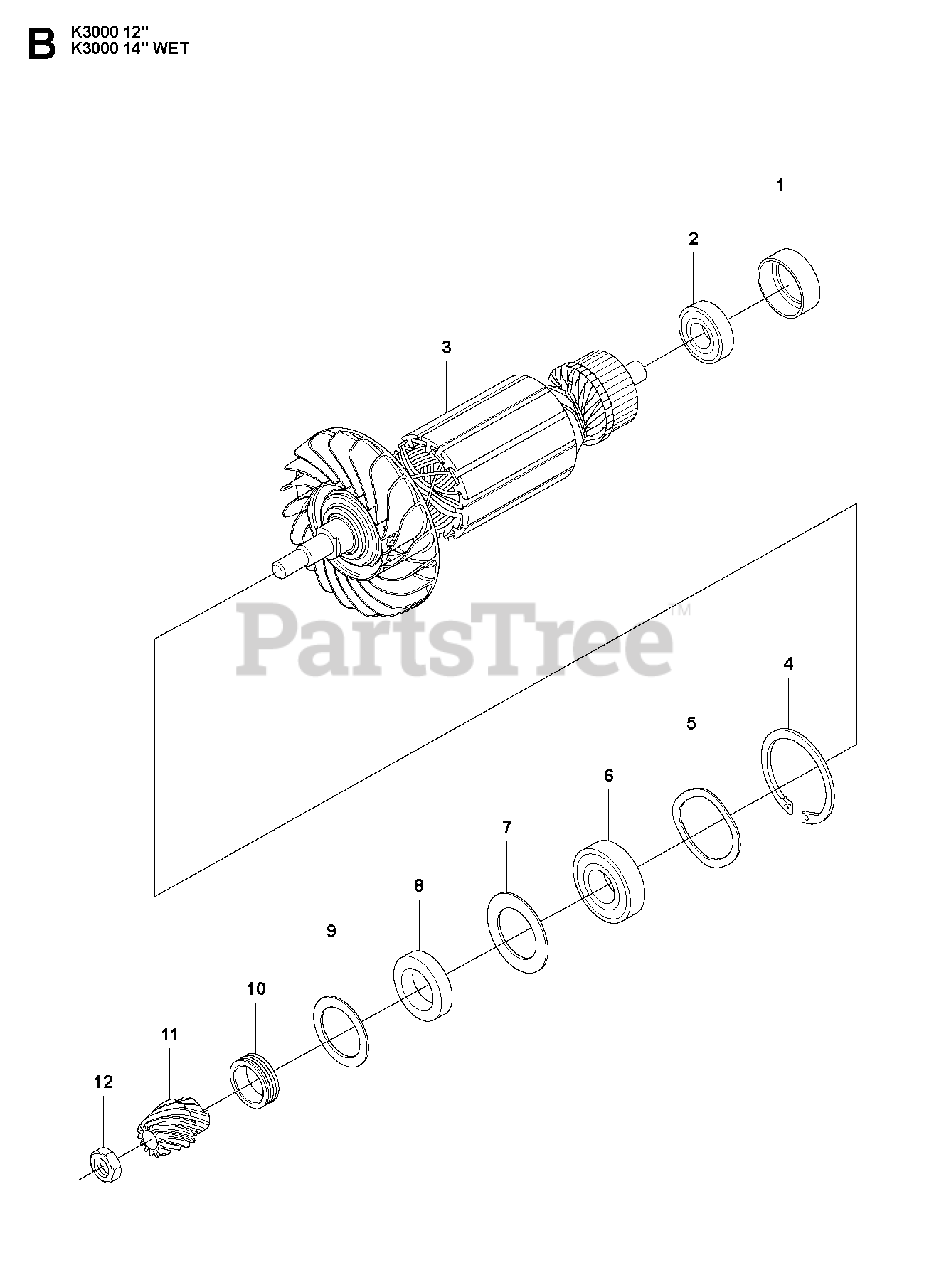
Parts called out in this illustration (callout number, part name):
1	RUBBER BUSHING
3	ROTOR100 - 120V
3	ROTOR230V
5	SPRING WASHER
6	BALL BEARING
12	NUT
